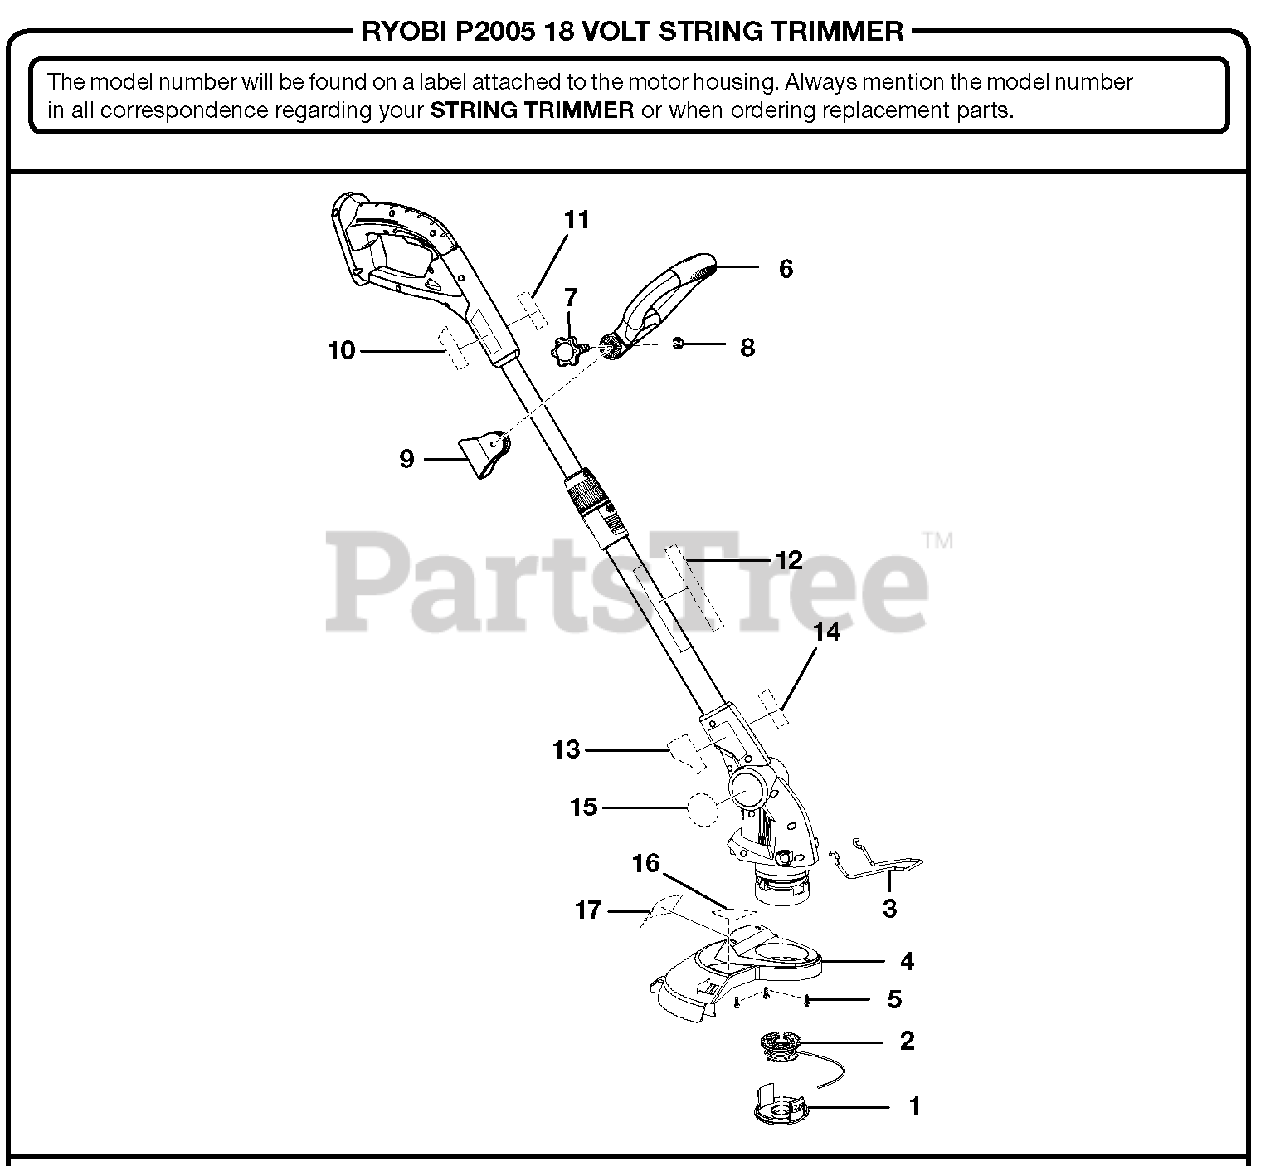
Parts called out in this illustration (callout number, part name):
1	Spool Cap (AC14HC)
2	Spool w/Line (AC14RSL)
3	Edger Guide
4	Grass Deflector Assembly
5	Screw (M4 x 10 mm)
6	Front Handle
7	Knob Screw (M6)
8	Hex Nut (M6)
10	Warning and Data Label Handle)
11	Logo Label (Handle)
12	Warning Label (Icon)
13	Warning Label (French/Spanish)
14	18V Lithium Ion Label
15	Pivoting Head Label
16	Auto Line Feed Label
17	Logo Label (Shield)
